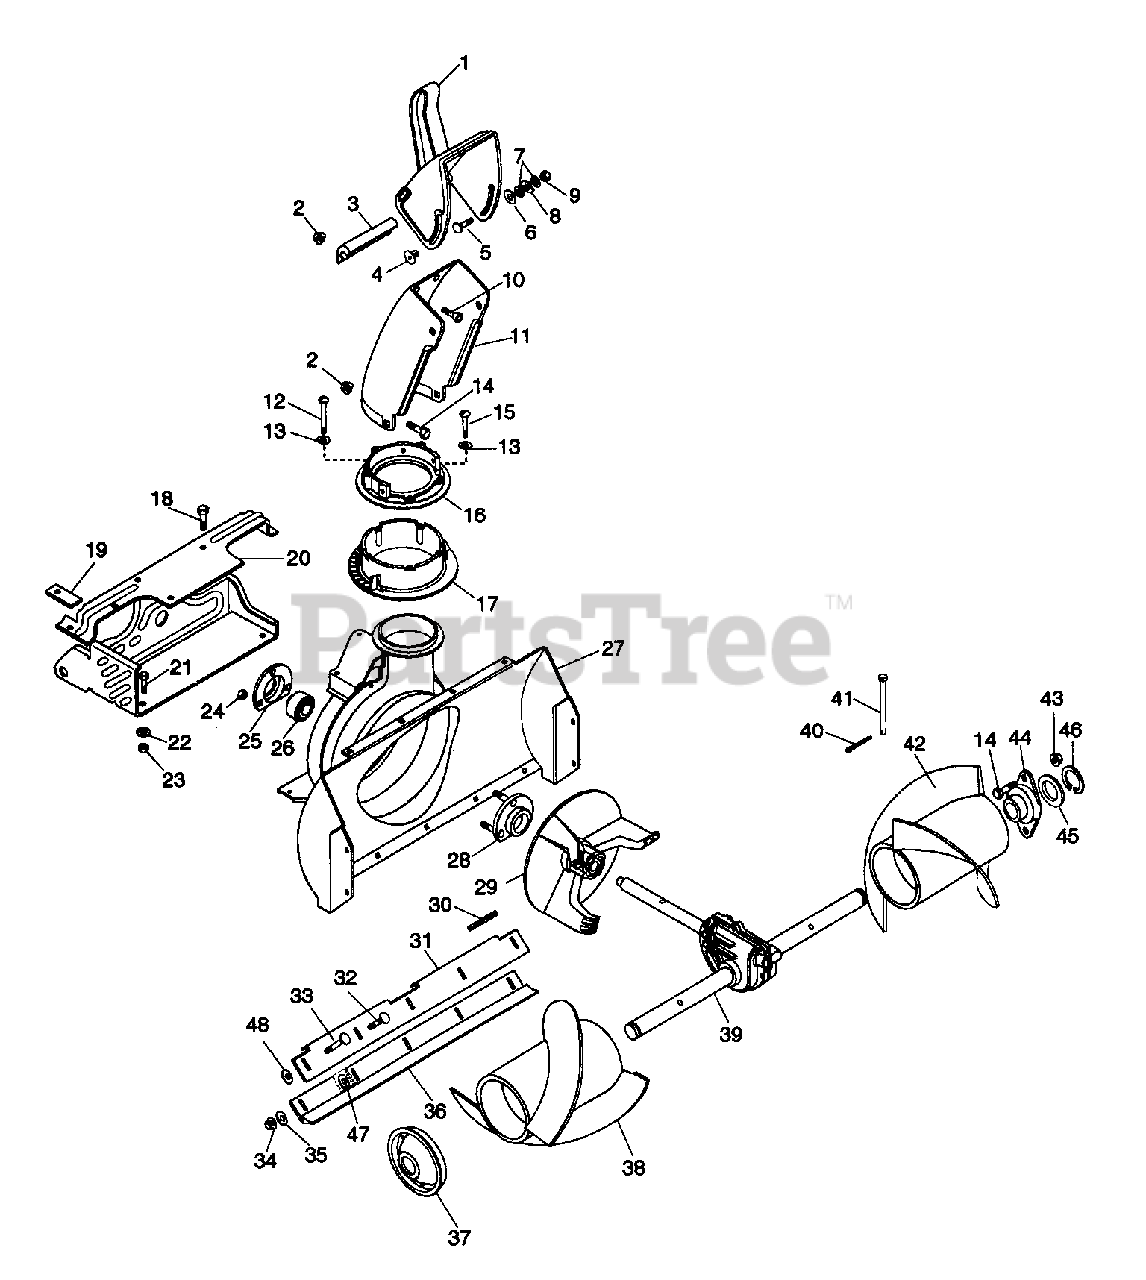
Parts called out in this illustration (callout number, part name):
1	DEFLECTOR CAP W/DECAL
2	NUT-LK-FLG .250-20 PL BLK
4	RVT-PUSH .28X.34 THRD-TRUSS-HD
5	BLT-RDHDSQNK .31-18X1.0 SHT PL
6	WSHR-PLASTIC .390X.875X.062
7	WSHR-FL-STL .323X.625X.062 PL
8	WAVE WASHER .390X.655X.110
9	NUT-LK .312-18 GR A PL
10	SCR-SKH .25-20X.50 FLTCNTRSK
11	DISCHARGE CHUTE
12	SCR-TAP 8-18X2.00 SL HWH PL B
13	WSHR-FL-NYL .31X.75X.180
14	BLT-HEX .25-20X.63 PL BLK GR5
15	SCR TAP 8-18X1.50 SL HWH PL B
17	CHUTE GEAR
18	SCR-TAP .312-18X.50 HWH PL TR
19	PAD-FOAM
20	FRAME WELDMENT
21	BLT-HEX .31-18X.63 PL GR 2
21	WSHR-LK .312X.097 PL HVY
23	NUT-HEX .312-18
24	NUT-LK-CTR .250-20 PL
25	BEARING FLANGE
26	BRG-BALL .750X1.750X.50
27	AUGER HOUSING
28	BEARING FLANGE
29	IMPELLER-3 BLADE
30	PIN-ROLL .250X2.00
31	SCRAPER SUPPORT
32	BLT-RDHDSQNK .25-20X.75 GR5PL
32	BLT-RDHDSQNK .25-20X.50
33	BLT-RDHDSQNK .25-20X.88 PL
34	NUT-LK-FLG .250-20 PL
35	WSHR-FL-STL .328X.875X.062 PL
36	SCRAPER BLADE
37	END CAP - AUGER
38	L.H. AUGER
39	GEAR CASE ASSEMBLY
40	PIN-COTR .06X.50
41	PIN-CLEV .25X4.5
42	R.H. AUGER
43	NUT-LK-FLG .250-20 PL BLK
44	BEARING SUPPORT
45	WSHR-FL-STL 1.010X1.505X.062PL
46	WSHR-FL-STL .281X.625X.065 PL
47	WSHR-FL-STL .328X.875X.062 PL
47	WSHR-FL-STL.281X.62X.065 PL
48	WSHR-FL-STL .380X.875X.179 PL
